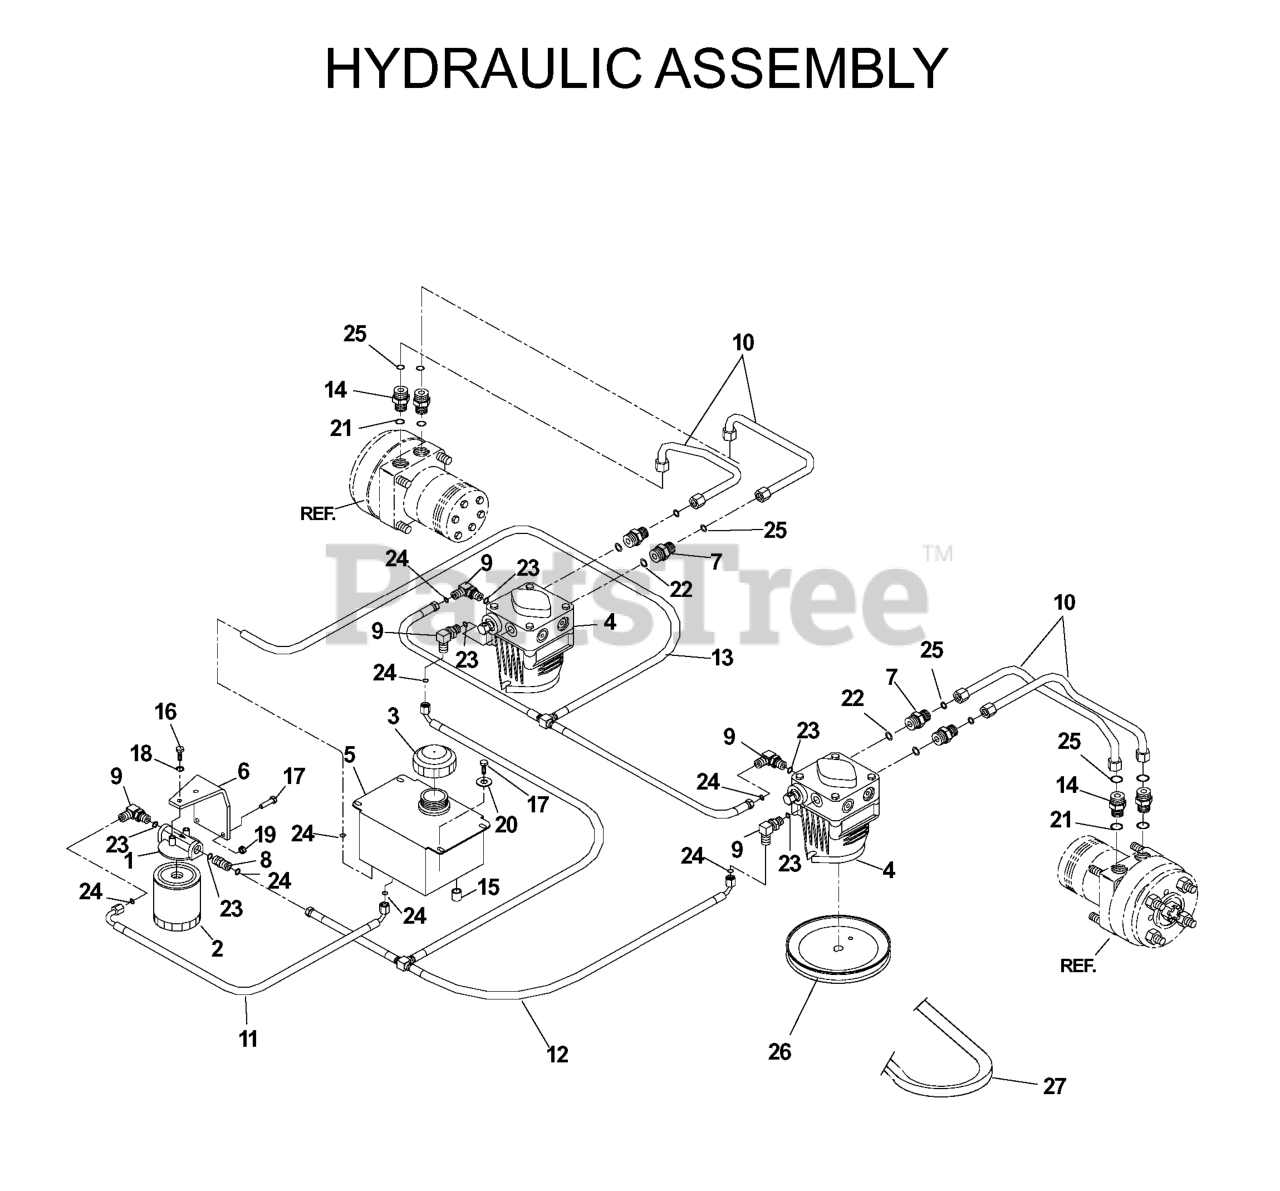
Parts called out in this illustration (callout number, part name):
1	FILTER HEAD
2	HYDRAULIC OIL FILTER
3	HYDRAULIC CAP
4	PUMP
6	OIL FILTER BRKT
7	FITTING, STRAIGHT F6400-8-8-0
8	STRAIGHT FITG
9	ELBOW, F6801-6-6-0 90 DEGREE
10	HYDRAULIC HOSE
12	TEE ASSEMBLY
13	TEE ASSEMBLY
15	NUT 9/16-18 JIC CAP
16	HCS 1/4C X 5/8
17	HCS 1/4C X 3/4 HCS
18	LOCKWASHER 1/4"
19	NUT.1/4-20.HEX.NYLOC.ZD
20	WASHER 1/4 FLAT
27	PUMP BELT
